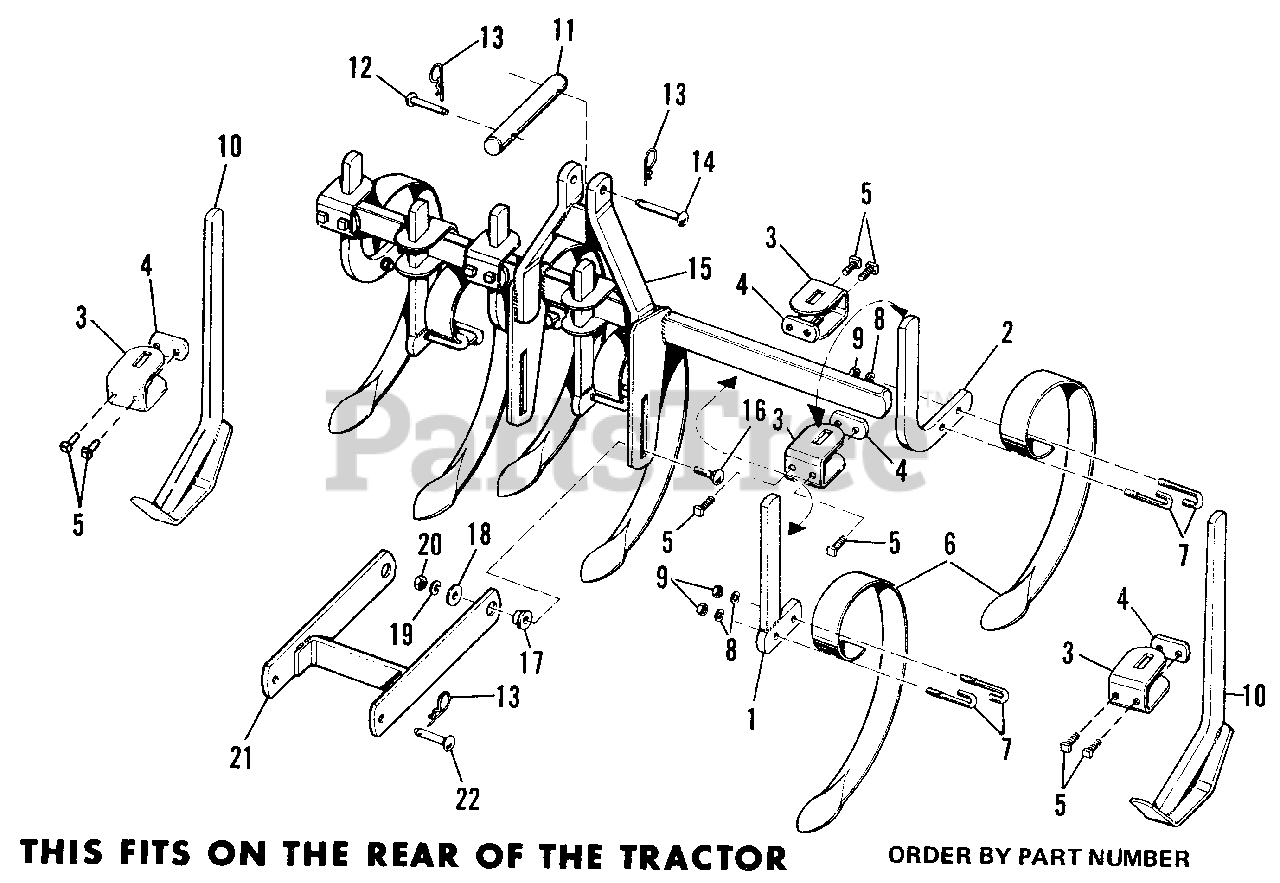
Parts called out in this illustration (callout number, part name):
1	Straight Standard Assembly
2	Standard Adjusting x 14"
3	Shank Clamp
4	Special Nut
5	Set Screw
6	Spring Tooth
7	Spring Tooth Bolt
8	Lockwasher
9	Full Hex Nut
10	Shoe Weld Assembly
11	Attaching Rod
12	Pin
13	Spring Clip
15	Rear Tool Bar Assembly
16	Carriage Bolt
19	Lockwasher
20	Full Hex Nut
21	Arm Assembly
22	Round Head Pin
